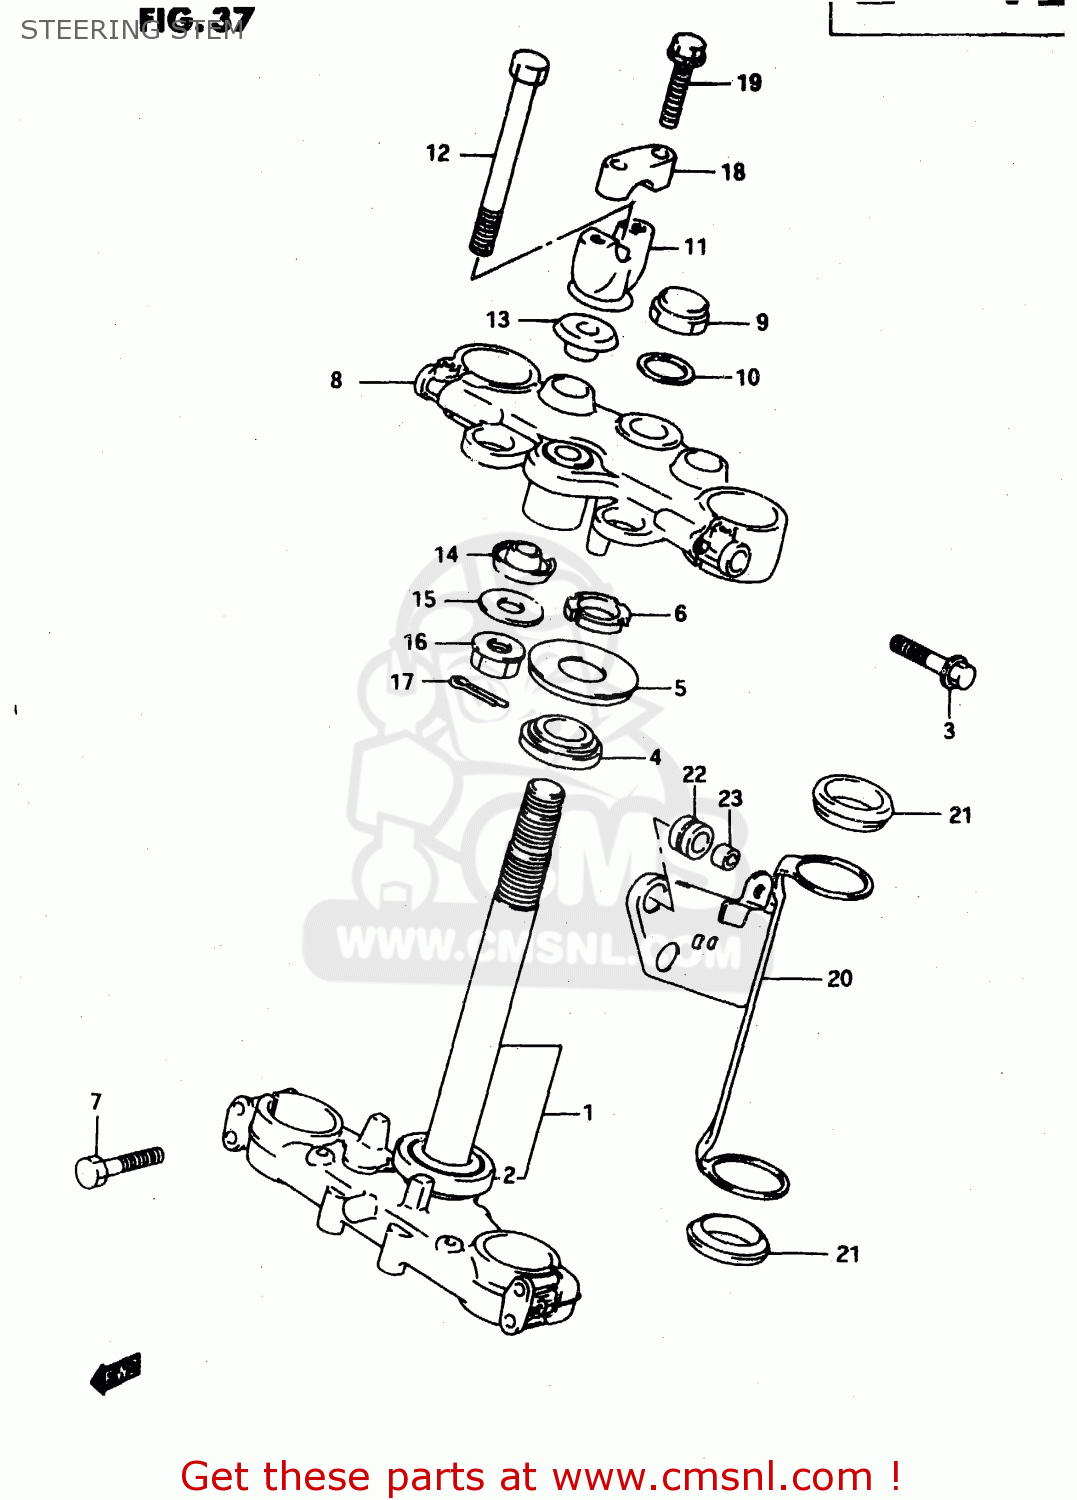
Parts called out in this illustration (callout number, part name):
1	STEM,STEERING
2	BEARING(30X55X17)
3	BOLT
4	TAPER,ROLLER BEARING
5	SEAL,STEERING UPR DUST
6	NUT,STEERING STEM
7	BOLT
8	HEAD,STEERING STEM
9	NUT,CAP
10	WASHER(22.5X32X1.6)
11	HOLDER,HANDLE LWR
12	BOLT
13	DAMPER,UPR
14	DAMPER,LWR
15	WASHER,HANDLEBAR HOLDER
16	NUT
17	COTTER PIN
18	HOLDER,HANDLE UPR
19	BOLT
20	COVER,FORK,R
21	CUSHION,HEADLAMP BRACKET
22	CUSHION
23	SPACER (6.8X10X10)
